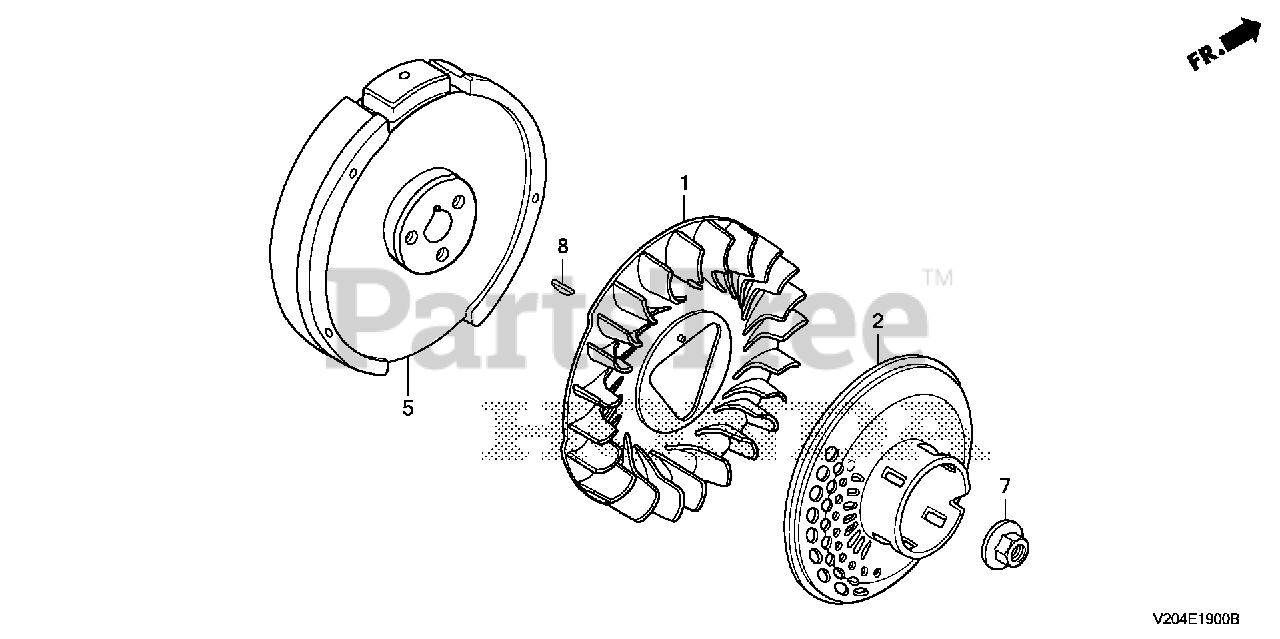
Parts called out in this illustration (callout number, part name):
1	FAN, COOLING
2	PULLEY, STARTER (SCREEN GRID)
7	NUT, SPECIAL (16MM)
8	KEY, SPECIAL WOODRUFF (25X18)
